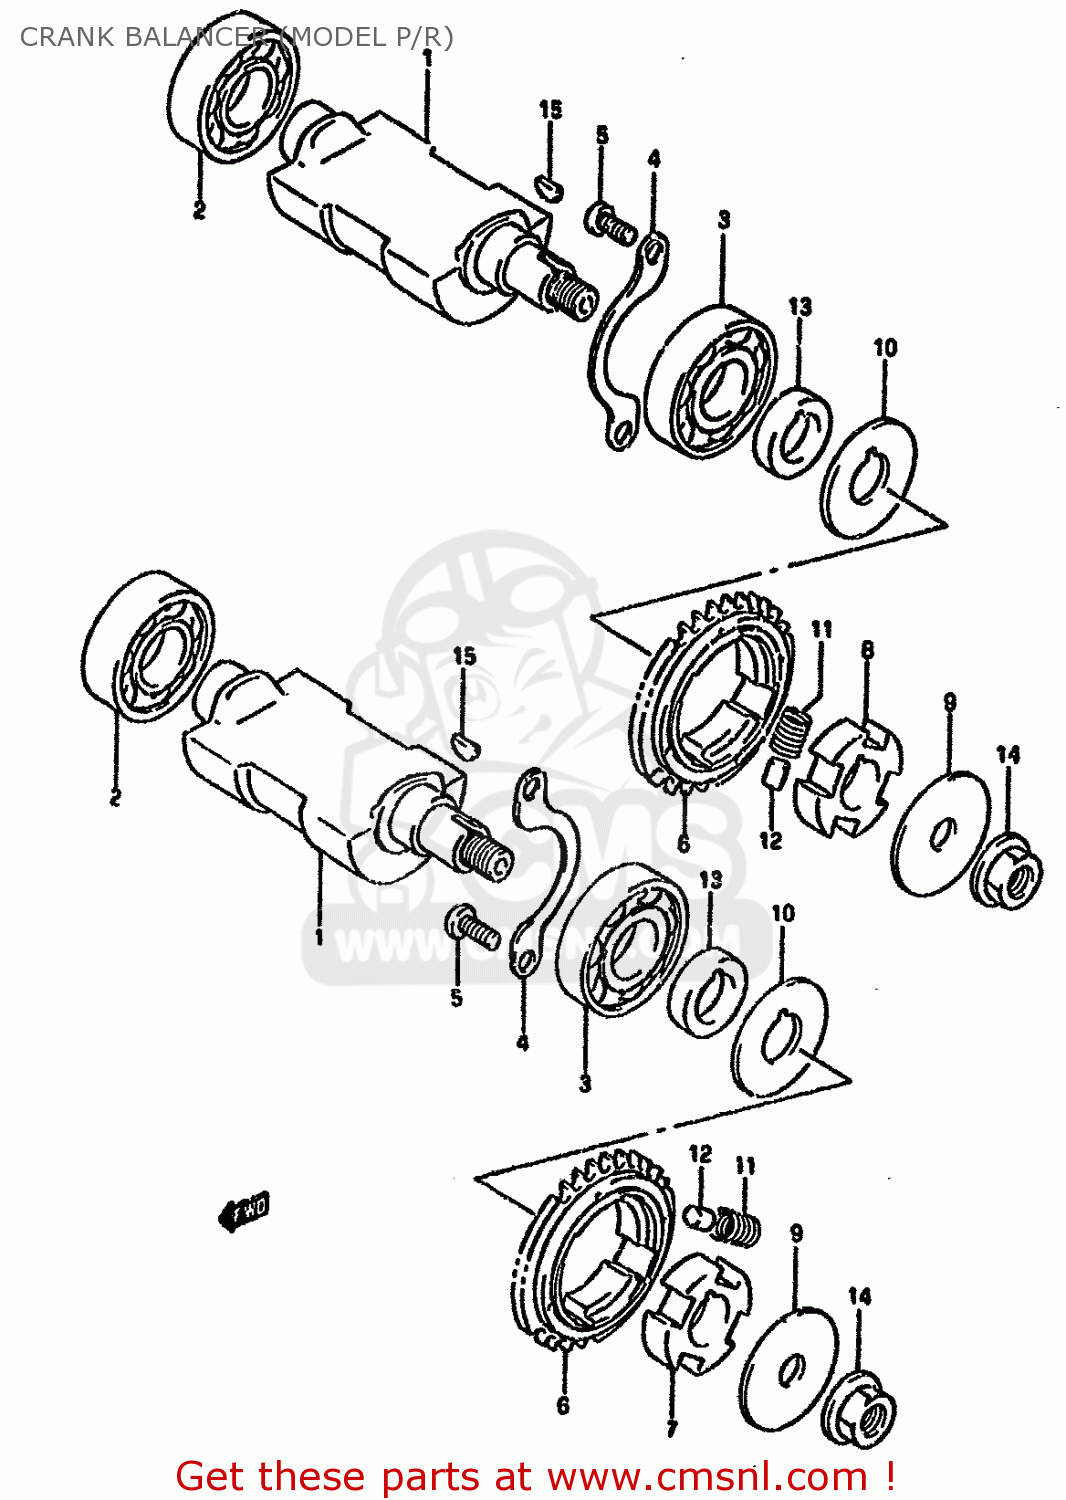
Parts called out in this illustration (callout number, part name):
1	BALANCER,CRANK
2	BEARING(20X42X12)
3	BEARING(20X47X12)
4	RETAINER,CRANK BAL BEARING
5	SCREW
6	SPROCKET,BALANCER DRIVE
7	RACE,CRANK BALANCER
8	RACE,INNER REAR
9	WASHER (10X39X1.6)
10	WASHER
11	SPRING
12	PIN(6X8.8)
13	SPACER (16X26X7.5)
14	NUT
15	KEY
